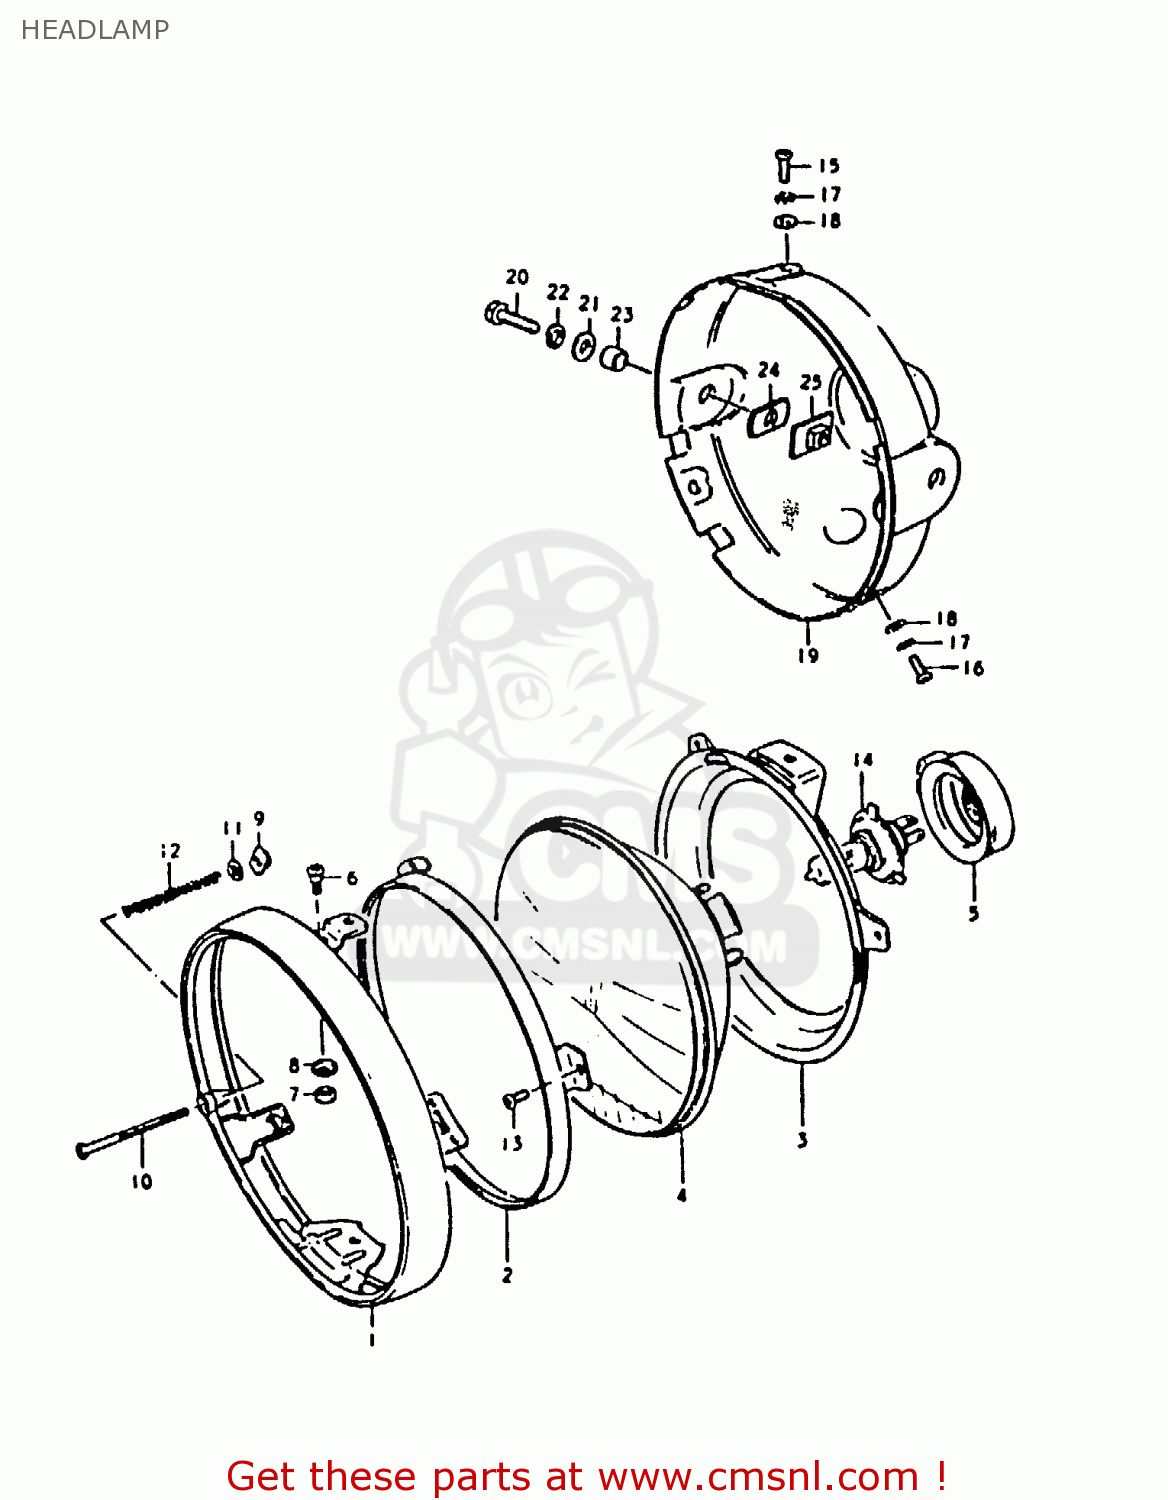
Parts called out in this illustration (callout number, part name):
1	RIM
2	RETAINER
3	RING,HEADLAMP UNIT
4	LAMP UNIT
5	COVER,HEADLAMP SOCKET
6	SCREW
7	NUT,ADJUSTING
8	SPACER
9	NUT
10	SCREW,HEADLAMP ADJUST
11	WASHER
12	SPRING,HEADLAMP ADJUST
13	SCREW
14	BULB(12V60/55W,H4)
15	BOLT
16	SCREW
17	LOCK WASHER
18	WASHER
19	HOUSING,HEADLAMP(BLACK)
20	BOLT
21	WASHER
22	LOCK WASHER
23	SPACER (8.8X12X7)
24	CUSHION
25	PLATE,HEADLAMP HOUSING
